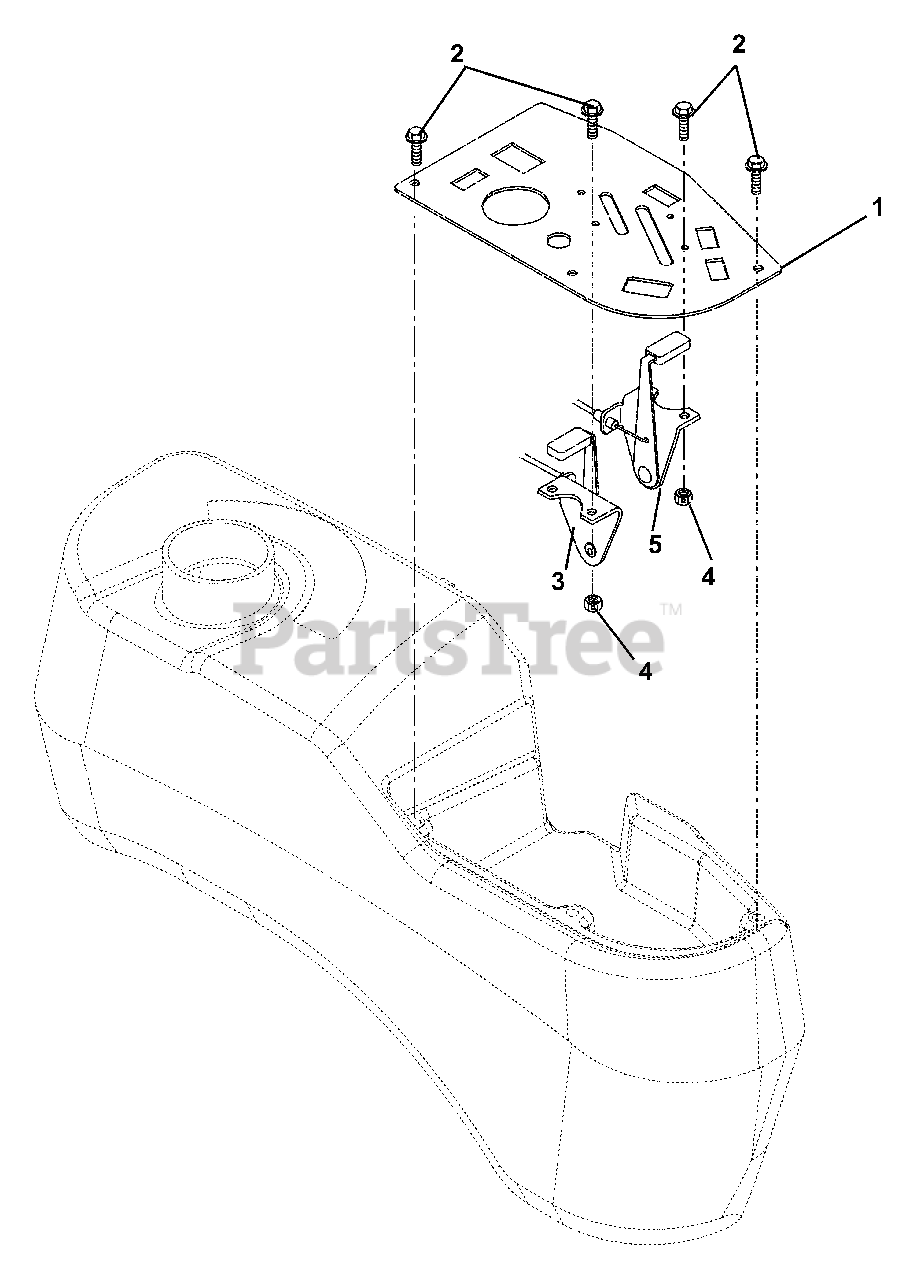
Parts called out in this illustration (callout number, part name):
1	Panel-Control
2	Screw-Machine 10-24 x .50 Hex Washer Head (075, 076, 318, 319)
2	Screw-Machine 10-24 x .50 Hex Washer Head (073, 074)
3	Throttle, Control (075, 076, 318, 319)
3	Throttle, Control (073, 074)
4	Nut-Locking-Nylon 10-24 With Insert (075, 076, 318, 319)
4	Nut-Locking-Nylon 10-24 With Insert (073, 074)
5	Choke Control (073, 074)
